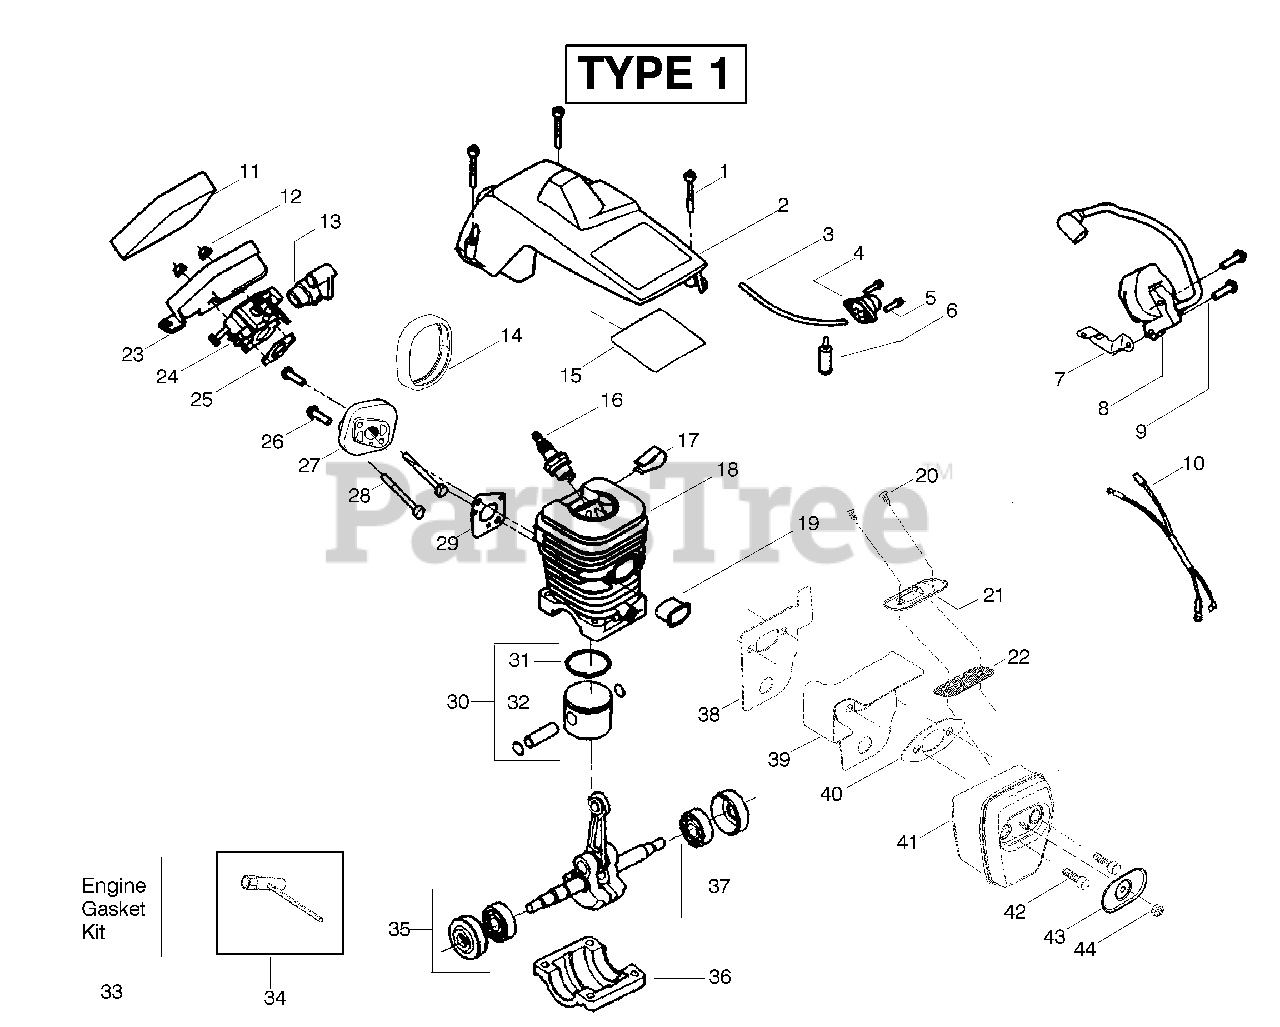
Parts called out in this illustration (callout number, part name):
2	Assy-Cylinder Shield
3	Kit-Fuel Line
4	Assy- Air Purge
6	Assy-Fuel Pick-up
7	Strap-Ground
8	Ignition Module
10	Assy-Wire Harness
11	Foam- Air Filter
13	Grommet-Carb Adjust
14	Seal-Carb Adapter
15	Reflector-Heat
16	Spark Plug
17	Clip-High Tension Lead
18	Kit-Cylinder
19	Insulator-Heat
20	Screw-Outlet cover
21	Cover - Outlet
22	Kit-Spark Arrestor
23	Air Filter Housing
24	Kit-Carburetor (WT-600)
24	Kit-Carburetor (WT-637)
25	Gasket-Carb.
27	Carb. Adapter
29	Gasket-Carb Adaptor
30	Kit-Piston
31	Ring-Piston
32	Retainer-Piston Pin
33	Kit-Engine Gasket
34	Bar Wrench
35	Assy-Seal & Bearing
36	Cap-Crankcase
37	Assy-Crankshaft
38	Backplate
39	Guide-Outlet
40	Gasket-Muffler
41	Assy-Muffler
42	Bolt-Muffler
43	Cover-Bolt
44	Nut-Brass
